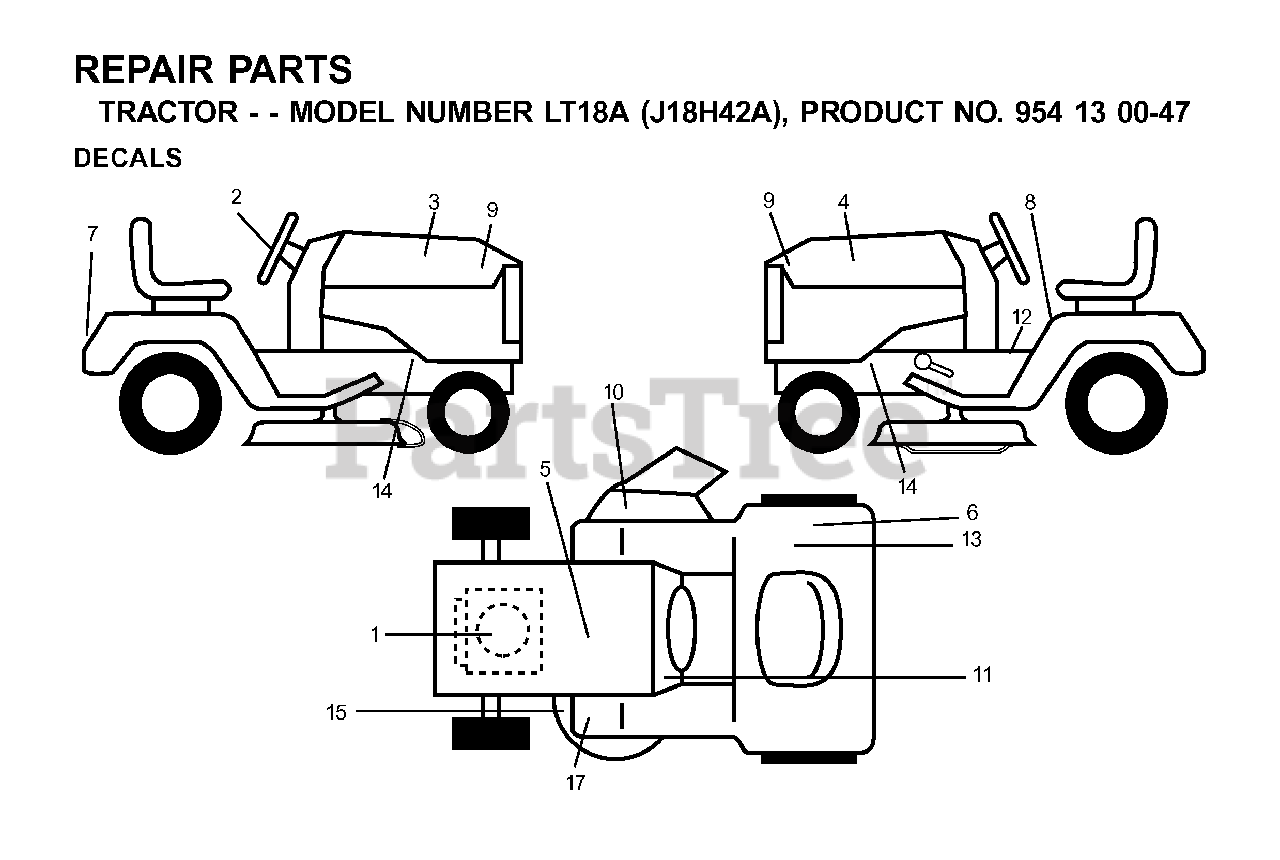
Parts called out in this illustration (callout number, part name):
5	DECAL BTRY SYMBOLS
6	DECAL CERTIFICATION
8	DECAL READ OWNER'S MAN SYMS
10	DECAL MOWER CUT/FINGER
12	DECAL PARK BRAKE
13	DECAL EUROPE STANDARD CE
15	DECAL V BELT SCHEMATIC
